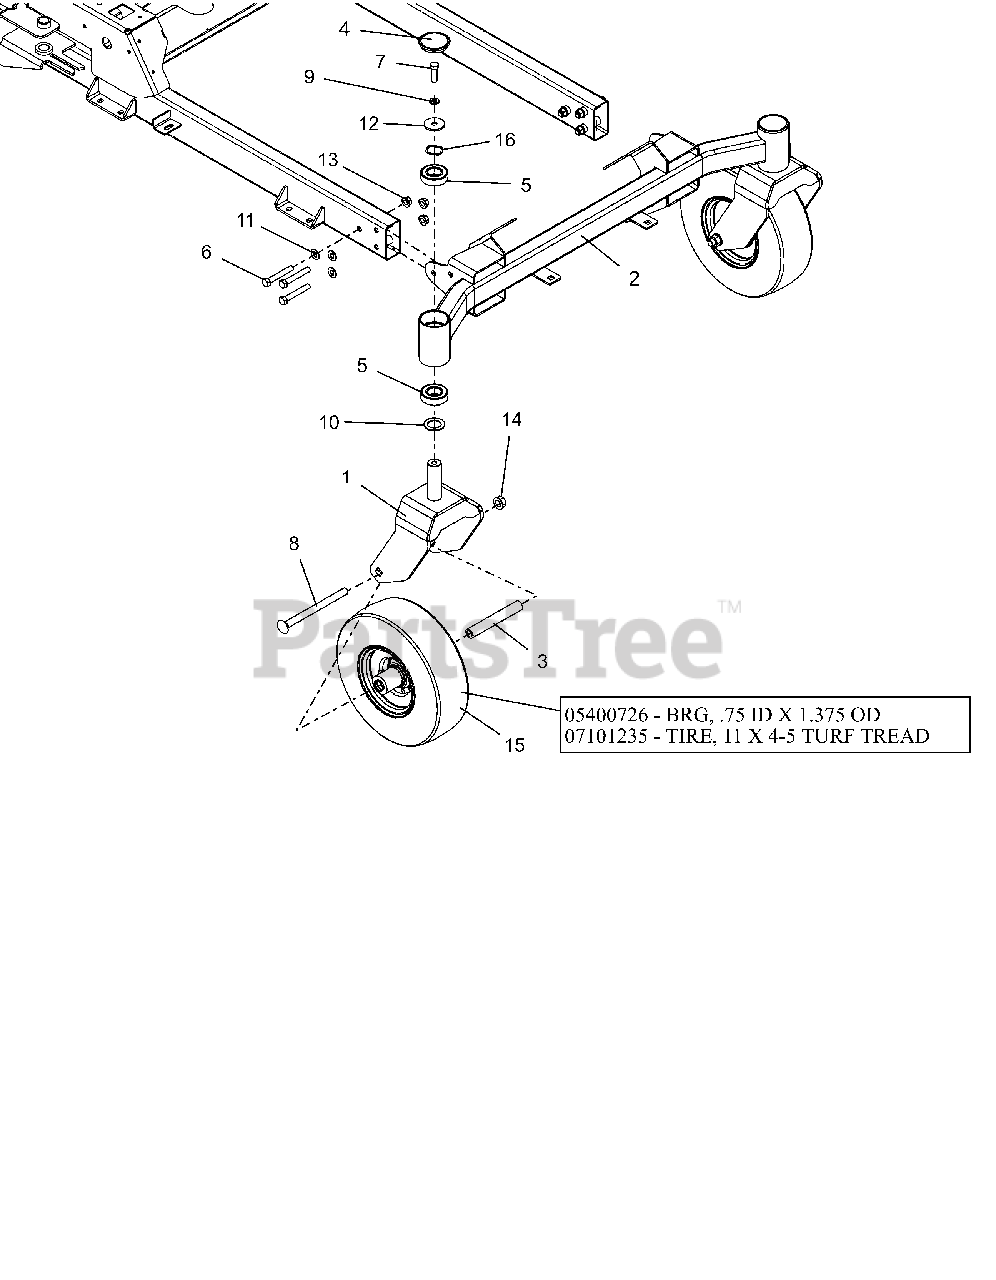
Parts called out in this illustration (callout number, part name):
1	WMT, CASTER FORK
2	WLDMT, AXLE FRONT
3	SPACER, ROLLED WHEEL
4	CAP, DUST
5	BRG,BALL 1.00X2.00X.563(1641)
6	BLT, HEX .38-16X2.50 G8 ZCC
7	BLT, HEX .38-16X1.25 G5 ZCC
8	BLT, RHSN .50-13X6.50 G5 ZCC
9	WSHR,LK-REG .375X.094 ZCC
10	WSHR-HRD-THRS 1.007X1.542X.062
11	WSHR-FL-STL 0.406X0.812X0.055 HRD
12	WSHR, FLT .380X1.50X.125 ZCC
13	NUT-LK-TOP-FLG .375-16 GG ZCC
14	NUT-LK-TOP-FLG .500-13 GF ZCC
15	ASM, WHL/TIRE 11X4.00-5
15	BRG, .75 ID X 1.375 OD
15	TIRE, 11X4-5 TURF TREAD
16	WSHR-WAVE 1.0X1.25X.028 .145FH
